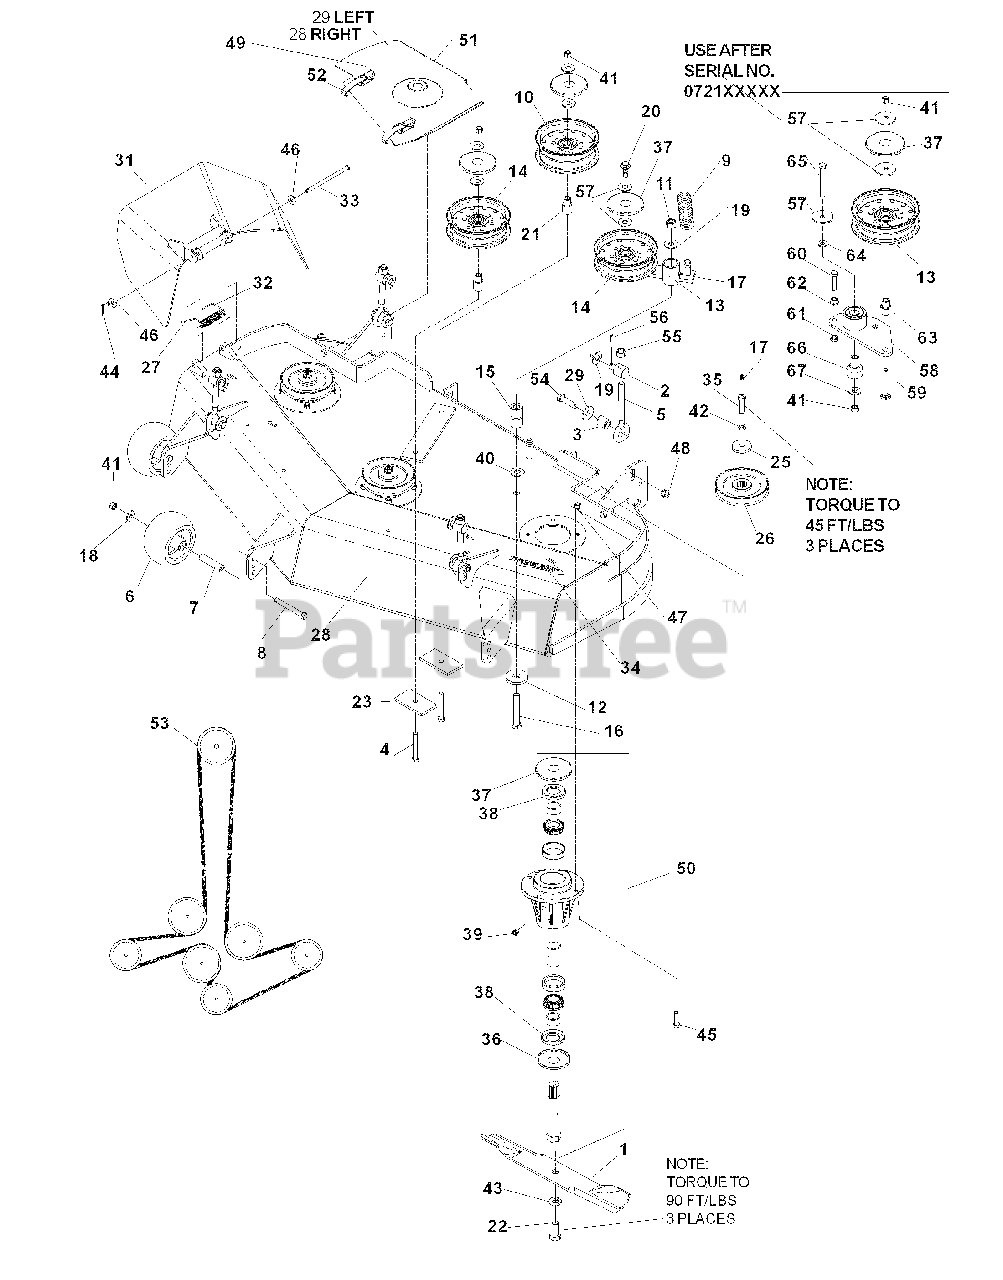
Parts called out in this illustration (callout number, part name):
1	BLADE, 16 1/4
4	HCS, 3/8 -16 x 2 3/4
6	ROLLER, ANTI SCALP
8	HCS, 3/8 -16 x 3 1/2, GR8
9	SPRING, EXTENSION
10	PULLEY, IDLER
11	NUT, 1/2 -13, NYLOC
12	WASHER, .65
14	PULLEY, IDLER
15	BUSHING, PIVOT
16	HCS, 1/2 -13 x 3 1/4
17	ZERK, STRAIGHT, 1/4 -28
18	WASHER, 3/8
19	WASHER, 9/16
20	HCS, 3/8 -16 x 1,
21	BUSHING, IDLER
22	HCS, 5/8 -18 x 1 1/4
23	PAD
24	SPRING WASHER, 1/2
25	WASHER, .469
26	PULLEY
27	CAP-SLEEVE
28	DECK W/DECALS
29	BELT SHIELD, RIGHT
30	BELT SHIELD, LEFT
31	DISCHARGE CHUTE
32	SPRING, TORSION
33	PIN-CLEVIS, 5/16 DIA x 5.19
34	DECAL, TUNNEL RAM
35	HCS, 7/16 -20 x 1 1/2, GR8
36	BOTTOM DUST CAP
37	TOP DUST CAP
38	SHAFT SEAL
39	PLUG, VENTED
40	WASHER, 1/2
41	NUT, 3/8 -16, NYLOC
42	LOCKWASHER, 7/16
43	LOCKWASHER, 5/8
44	PIN COTTER, 1/8 x 3/4
45	HCS, 5/16 -18 x 1 1/4
46	WASHER, 5/16
47	NUT, 5/16 -18, NYLOC
48	NUT, 7/16 -14, CNTRLCK, GR A
49	DECAL, EURO SEVERING
50	SPINDLE ASSEMBLY
52	DRAW LATCH
54	HCS, 7/16 -14 x 1 3/4
55	NUT, 1/2 -13, NYLOC
56	PIN COTTER, 1/8 x 1
57	WASHER, 3/8, SPEC
58	ARM, IDLER, W/BEARINGS
59	RHSNB, 3/8-16 x 2 3/4,
60	HCS, 3/8-16 x 1 1/2, GR8
61	NUT, 3/8-16, JAM
62	NUT, 3/8-16, WHIZLK
63	BUSHING, IDLER
64	WASHER, 3/8, SAE
65	HCS, 3/8-16 x 3
66	PIVOT, BEARING
67	WASHER, 3/8
